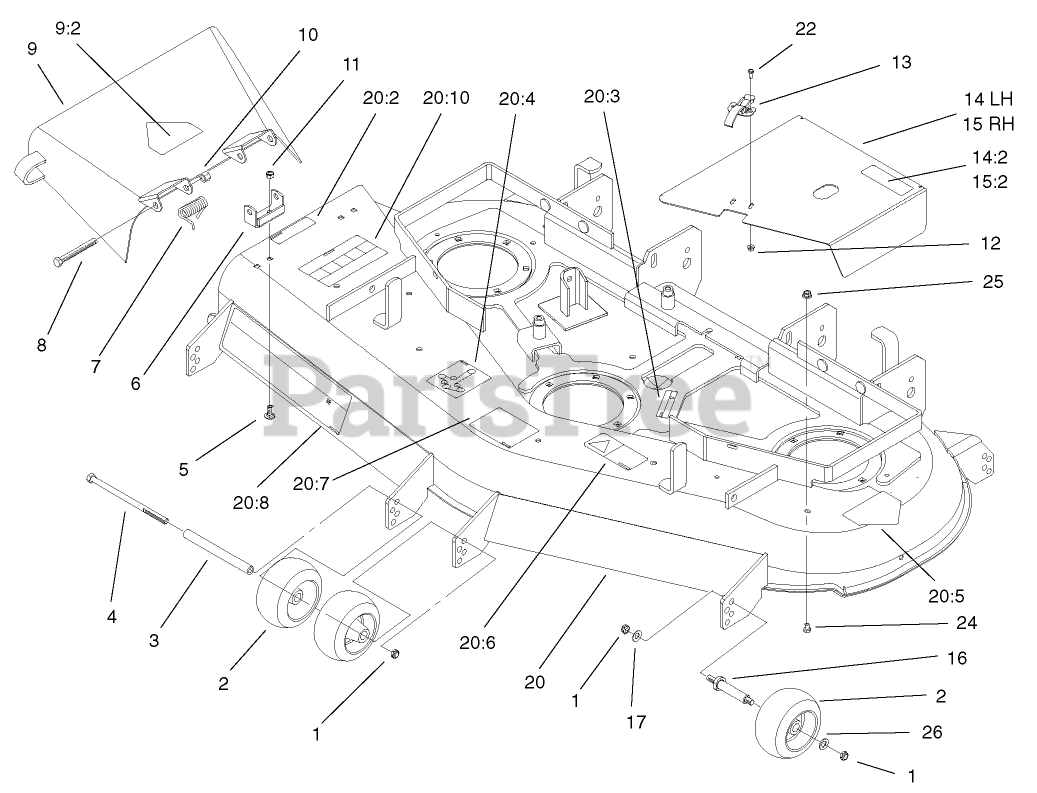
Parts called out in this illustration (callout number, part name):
1	NUT-HHF, WHIZ
2	WHEEL-GAGE
3	SPACER-WHEEL
4	SCREW-HH
5	SCREW-CARR
6	BRACKET-PIVOT
7	SPRING
8	SCREW-HH
9	DEFLECTOR ASM, 52" W/DECAL
9:2	DECAL-DANGER
10	NUT-HEX
11	NUT-LOCK, CONE
12	NUT-LOCK, FLANGE
13	CLAMP-SLOTTED
14	LH COVER ASM
14:2	DECAL-DANGER
15	RH COVER ASM
15:2	DECAL-DANGER
16	SPACER
17	Washer
18	WASHER-BELLEVILLE
19	SCREW-HH
20	52" Deck ASM
20:2	DECAL-DANGER
20:3	DECAL-COVER, MISSING
20:4	DECAL-ROUTING, BELT
20:5	DECAL-DANGER
20:6	DECAL-TORQUE, BLADE BOLT
20:7	DECAL-WHEEL, GAGE
20:8	DECAL
20:10	DECAL-DANGER, THROWN OBJECT
21	SPACER-WHEEL
22	SCREW-HWH
24	SCREW-HH
25	NUT-HF
26	Washer
